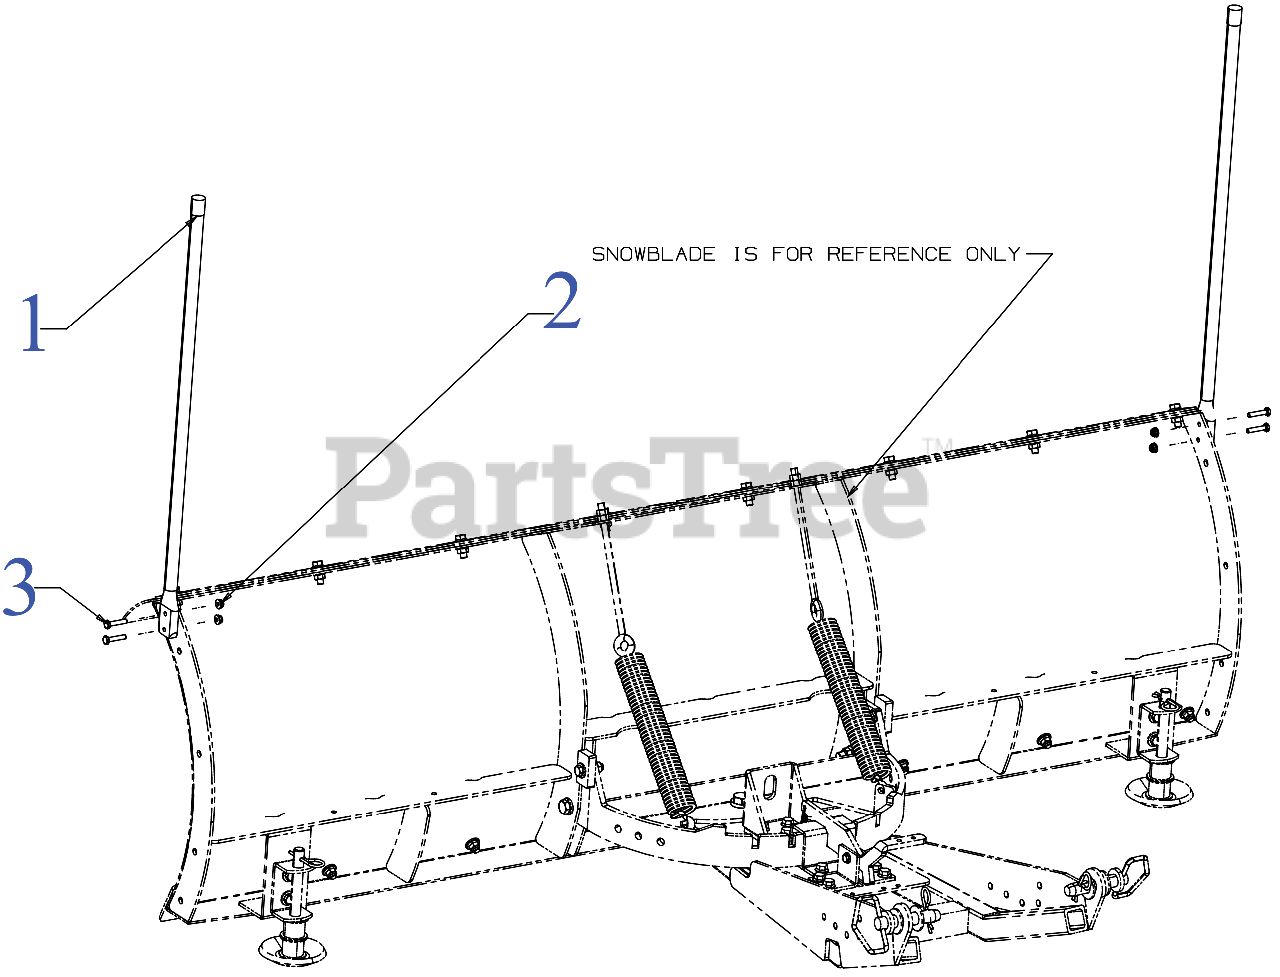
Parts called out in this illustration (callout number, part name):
1	FLAG MARKERS SET (2 PIECES)
2	HEX SCREW 1/4-20 x 1.25
3	FLANGE LOCK NUT
